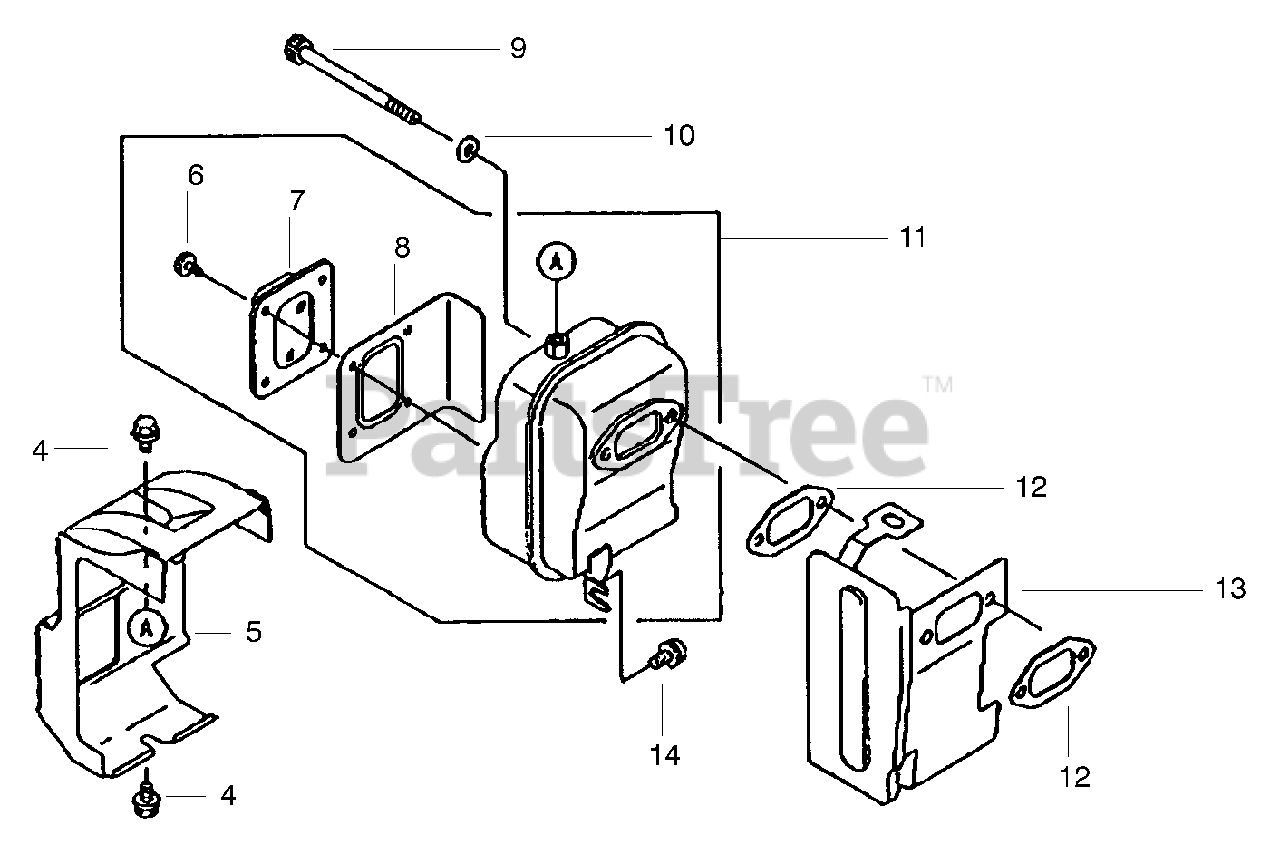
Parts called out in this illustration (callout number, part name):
5	Cover-Muffler
7	Arrestor-Spark
11	Assy-Muffler
13	Cover-Muffler
